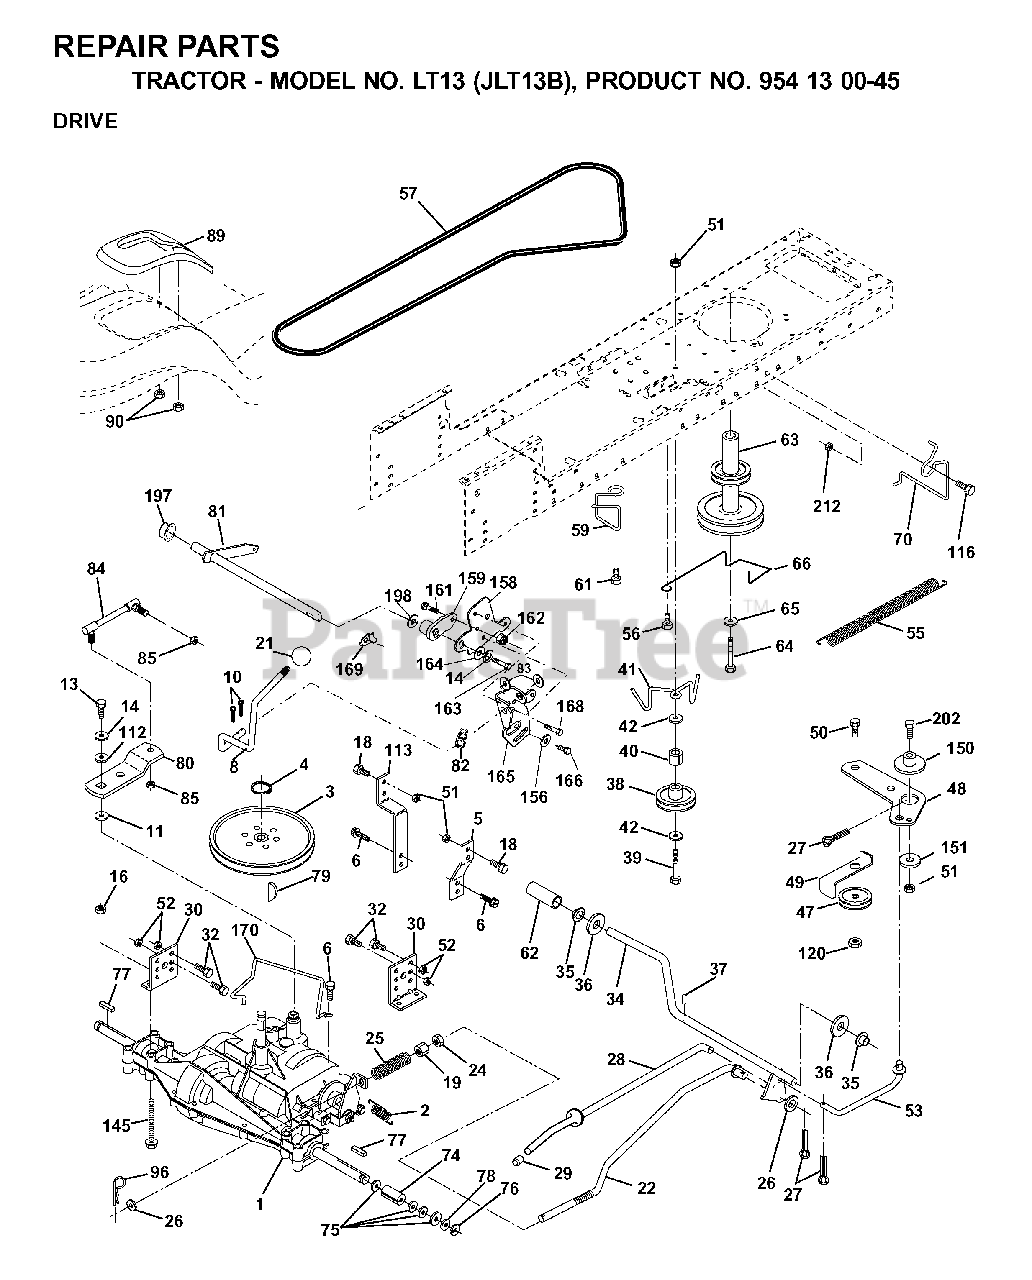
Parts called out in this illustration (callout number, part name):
2	SPRING,BRAKE RETURN
3	PULLEY TRANS
4	RETAINING RING LT
5	STRAP TORQUE
6	SCREW 5/16"
8	ROD SHIFT FENDER ADJUST STLT
10	PIN COTTER
11	WASH-SHFT PLT LT
13	BOLT 1/4-28X3/4
14	LOCKWASHER
16	NUT.71038.31-18.HEX.NYLOCK
19	NUT
21	KNOB.DUCKHEAD.1/2
22	ROD BRAKE
24	NUT
25	SPRING ROD LT
27	COTTER PIN
28	ROD, PARKING BRAKE
29	PLUNGER CAP
30	BRKT, MOUNT TRNSAXLE
32	BOLT
34	SHAFT, FOOT PEDAL
35	BEARING.NYLON
36	WASHER LT
37	DRIVE PIN
38	PULLEY.FLAT
39	BOLT
40	SPACER, SPLIT
41	KEEPER, BELT IDLER
42	WASHER
47	IDLER PULLEY
48	BELLCRANK, CLUTCH
49	RETAIN BELT
50	BOLT
51	LOCKNUT
52	LOCKNUT
53	LINK, CLUTCH LT
55	SPRING, RETURN LT
57	V-BELT
59	KEEPER, BELT CENTER
61	SCREW 3/8-16X3/4
62	PEDAL COVER T
63	ENGINE PULLEY
64	BOLT
65	LOCKWASHER
66	KEEPER BELT ENGINE
70	KEEPER BELT ENG
74	SPACER AXLE
76	E-RING LT
77	SQUARE KEY
80	ARM SHIFT
82	SHIFT SPRING
83	WASHER
85	NUT LOCK CENTER 1/4 -28 FNTHD
89	CONSOLE.SHIFT.STLT.6SP.BLACK
96	RETAINER M
112	WASHER LT
113	STRAP TORQUE LH LT
116	BOLT D
120	NUT LOCK FLG 3/8-16 UNC
150	SPACER, RETAINER
151	WASHER 12/32X2X10GA
156	WASHER.SRRTD.5/16
158	BRACKET
159	HUB
161	BOLT
162	NUT.CROWNLOCK.1/4
165	RP BRACKET
168	BOLT.SHOULDER.5/16-18X
169	PLATE.FASTENING.CROSS.SHAFT
197	NYLINER SNAP 5/8" ID
198	WASHER.NYL.7/8IDX.105"HYD CR
202	BOLT
212	NUT
